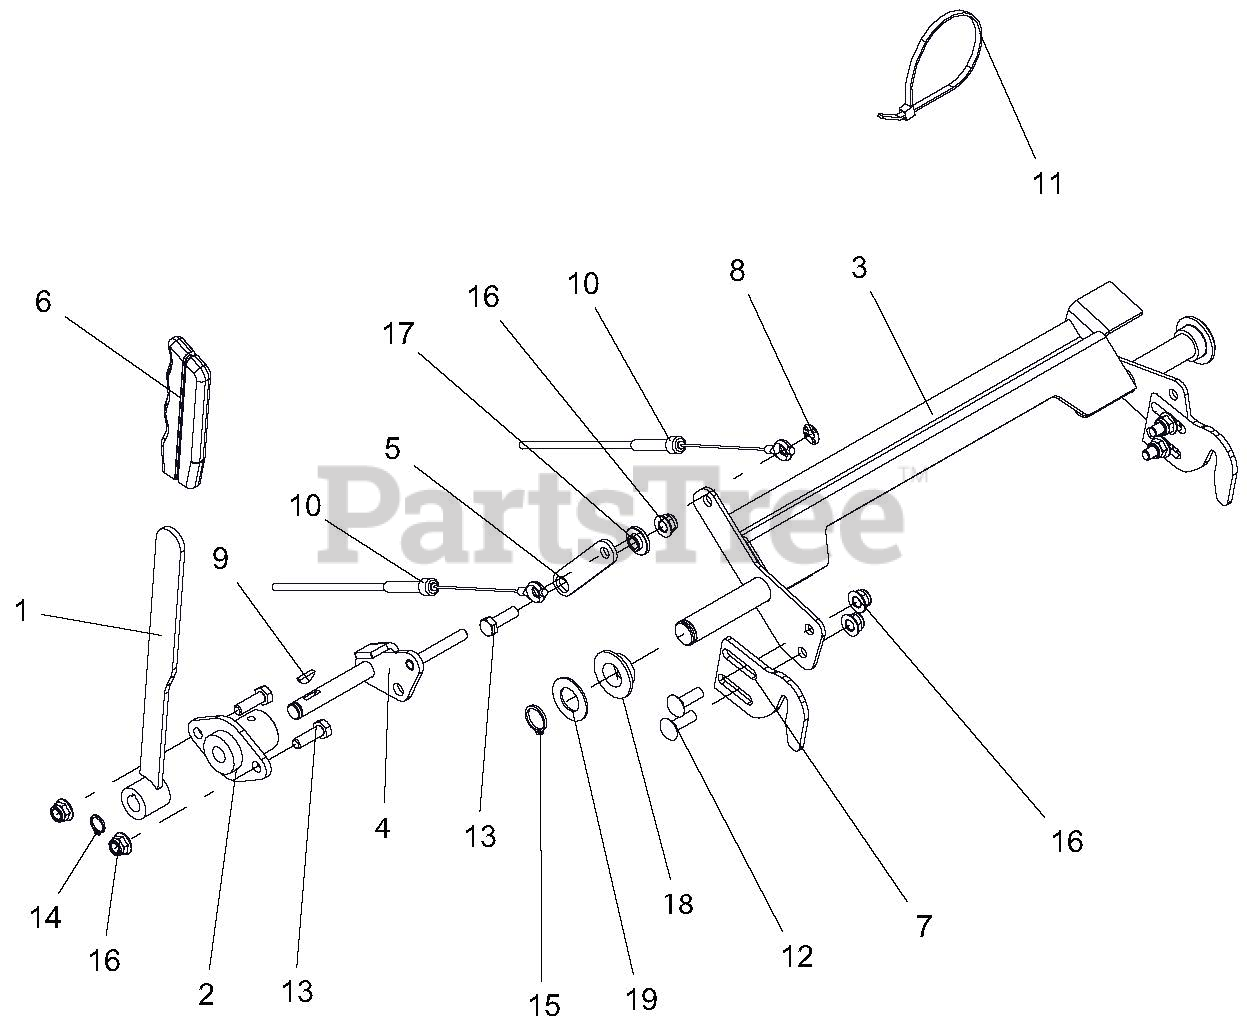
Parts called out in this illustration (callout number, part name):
1	WLDMT, PARKING BRAKE ARM
2	BSHG, FLANGE .500 ID
3	WLDMT, PT100 NEUTRAL LOCK
4	WLDMT, PARK BRAKE ARM
5	PLATE, NEUTRAL INTERLOCK
6	GRIP, PARKING BRAKE
7	NEUTRAL, LOCK LATCH-BLACK
8	NUT, PUSH .312
9	KEY, WDRF .13x.63 HRD#5 GM124545 P
10	CABLE, BRAKE ACTUATING
11	CABLE, TIE 5.50 LG
12	BLT-RDHDSQSHNK .31-18X1.00 G5 Y
13	BLT-HEX .31-18X1.00 GR5 YWZC
14	RG-RTNG-EXT .500x.050
15	RG-RTNG-EXT .750x.078
16	NUT-LK-NYL-FLG .31-18 YWZC
17	BSHG, FLG .325X.499X.26X.88
18	BSHG, FLANGE .762 X 1.48 X .44 NNYLO
19	WSHR-FL-STL .755X1.375X.062 YWZC
